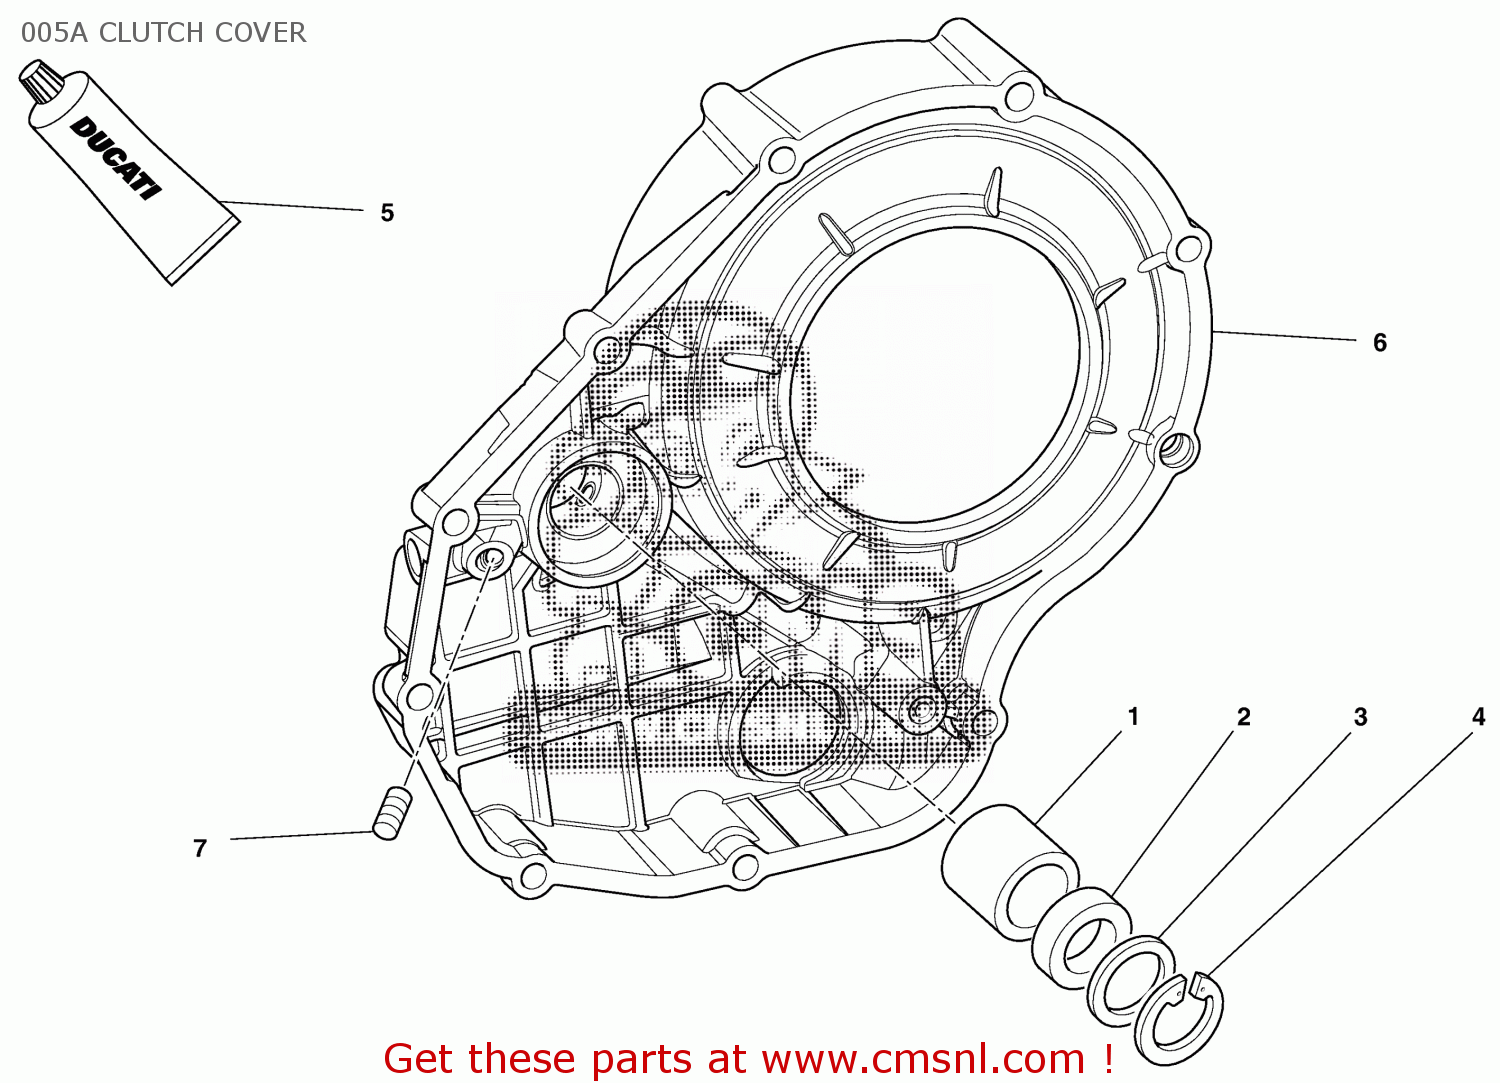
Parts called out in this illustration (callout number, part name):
1	BUSH
2	OIL SEAL
3	THRUST WASHER 20.8X37.8X1
4	CIRCLIP
5	LIQUID GASKET
6	CLUTCH COVER
7	THREADED DOWEL STEI M6X8
